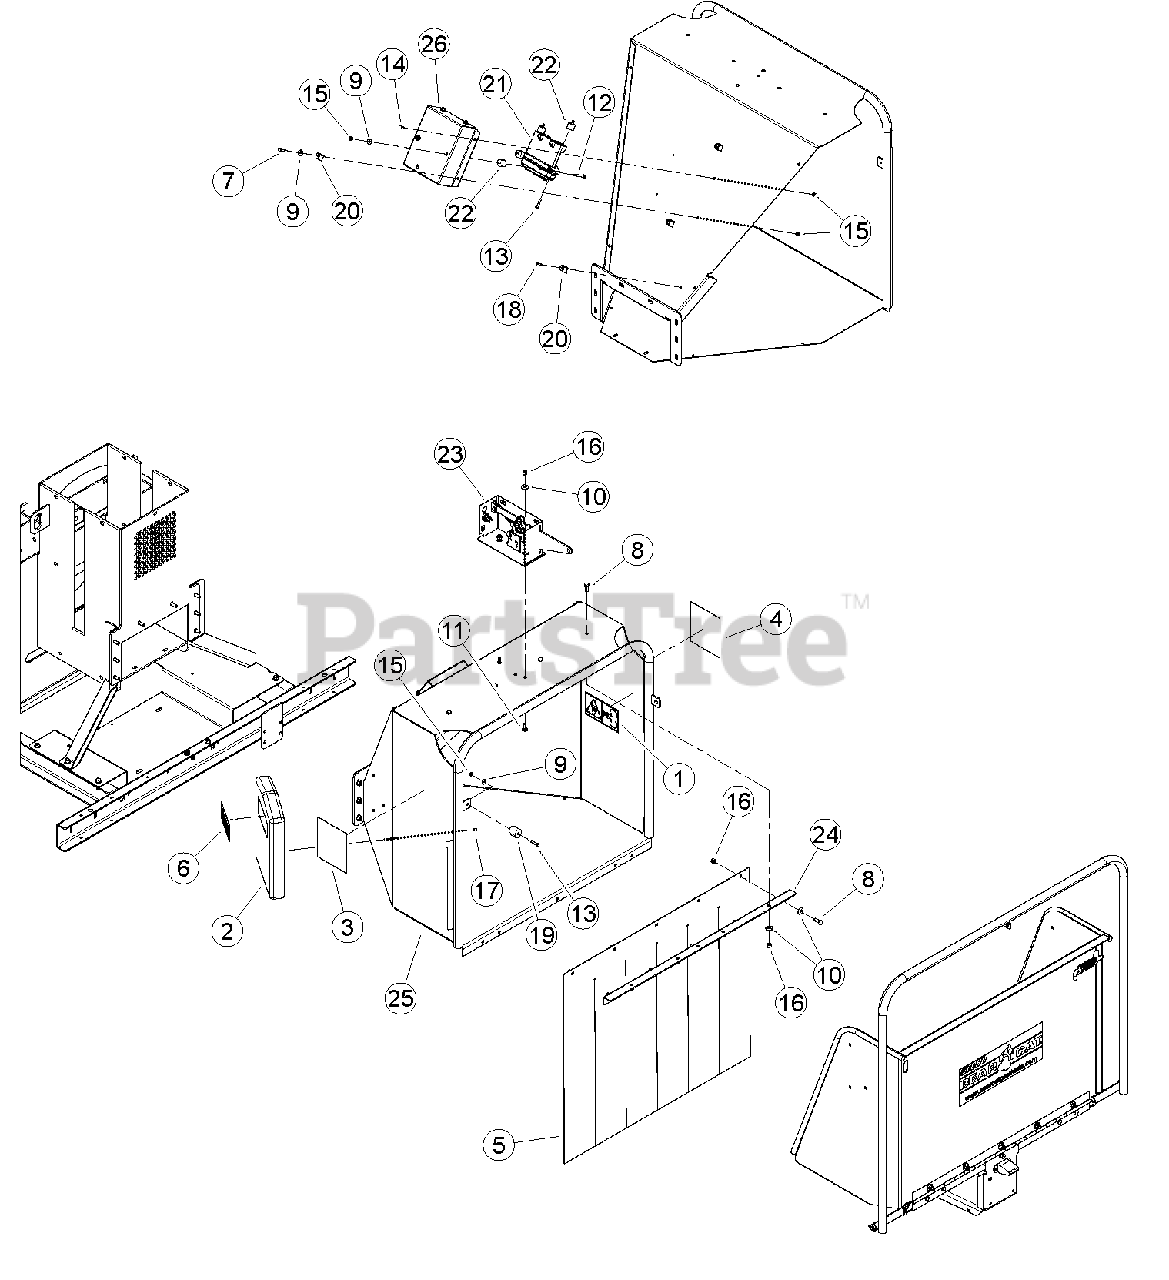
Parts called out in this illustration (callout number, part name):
1	DECAL, BLADE DANGER ISO
2	CONTAINER, INSTR. MANUAL
3	DECAL, FEED POSITION
4	DECAL, FEED POSITION
5	FLAP, CHUTE
6	DECAL, MUTILINGUAL MANUAL
7	BOLT, 1/4 X 1 GR5 HEX HD ZP
8	BOLT, 3/8 X 1 HEX HD GR5 ZP
9	WASHER, 1/4" FLAT ZP
10	WASHER, 3/8" FLAT ZP
11	BOLT, 3/8 X 1" GR5 CRG NC ZP
12	BOLT, 1/4 X 2-1/4 G5 HCS ZP
13	BOLT, 1/4-20 X 1-1/4 GR5 HHCS MAGNI 565 SILVER
14	BOLT, 1/4 X 5/8" HHCS GR5 ZP
15	NUT, 1/4" NE NYLOCK ZP
16	NUT, 3/8" NE NYLOCK ZP
17	RIVET, AL BLIND 1/4 X 1/2 DOME HEAD
18	RIVET, AL BLIND 1/4 X 3/4 DOME HEAD
19	BUMPER, RECESSED RUBBER
20	CLAMP, CABLE MOUNT
21	CONTROLLER, PLUS 1 CHIPPER
22	BUMPER, 1" OD W/ 1/4" STUD
23	ASSEMBLY, SWITCH BOX
24	SUPPORT, CHIPPER FLAP
25	WELDMENT, CHIPPER CHUTE
26	ENCLOSURE, PLUS 1 MOUNT
